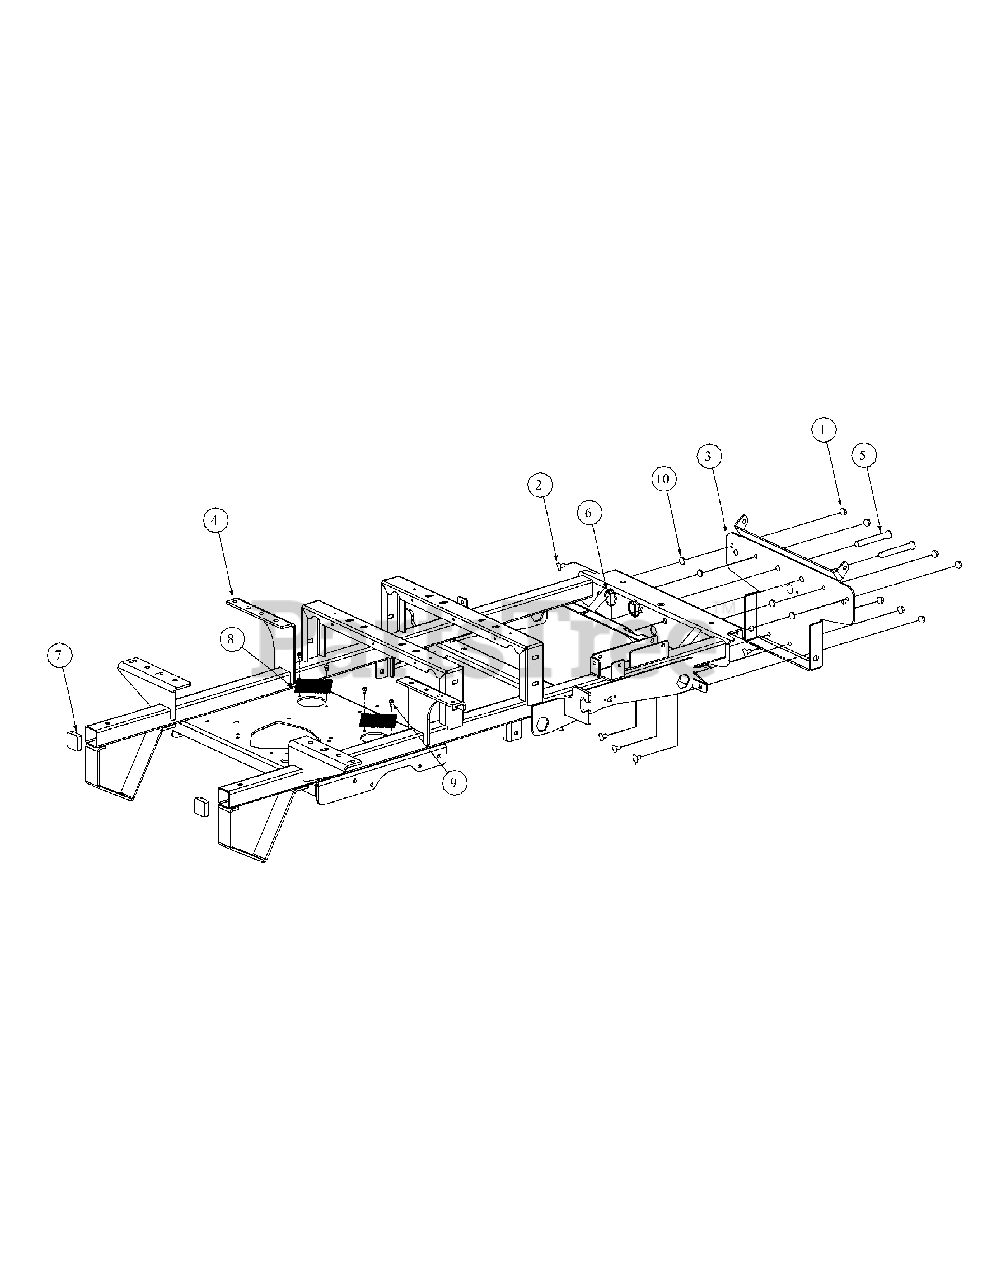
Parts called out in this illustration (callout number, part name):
1	Hex Nut, 3/8-16 Flange Lock
2	Carriage Bolt, 3/8-16 x .75 Long
3	Bracket Assembly, Frame, Front
4	Frame Assembly
5	Clevis Pin, .625 Dia x 4.375 Long
6	Linch Pin, 3/16 Dia.
7	Plug, Square Tube
8	Cover, Hydro Fan
9	Screw, TT, 1/4-20, 0.5
10	Push Retainer, 3/8
